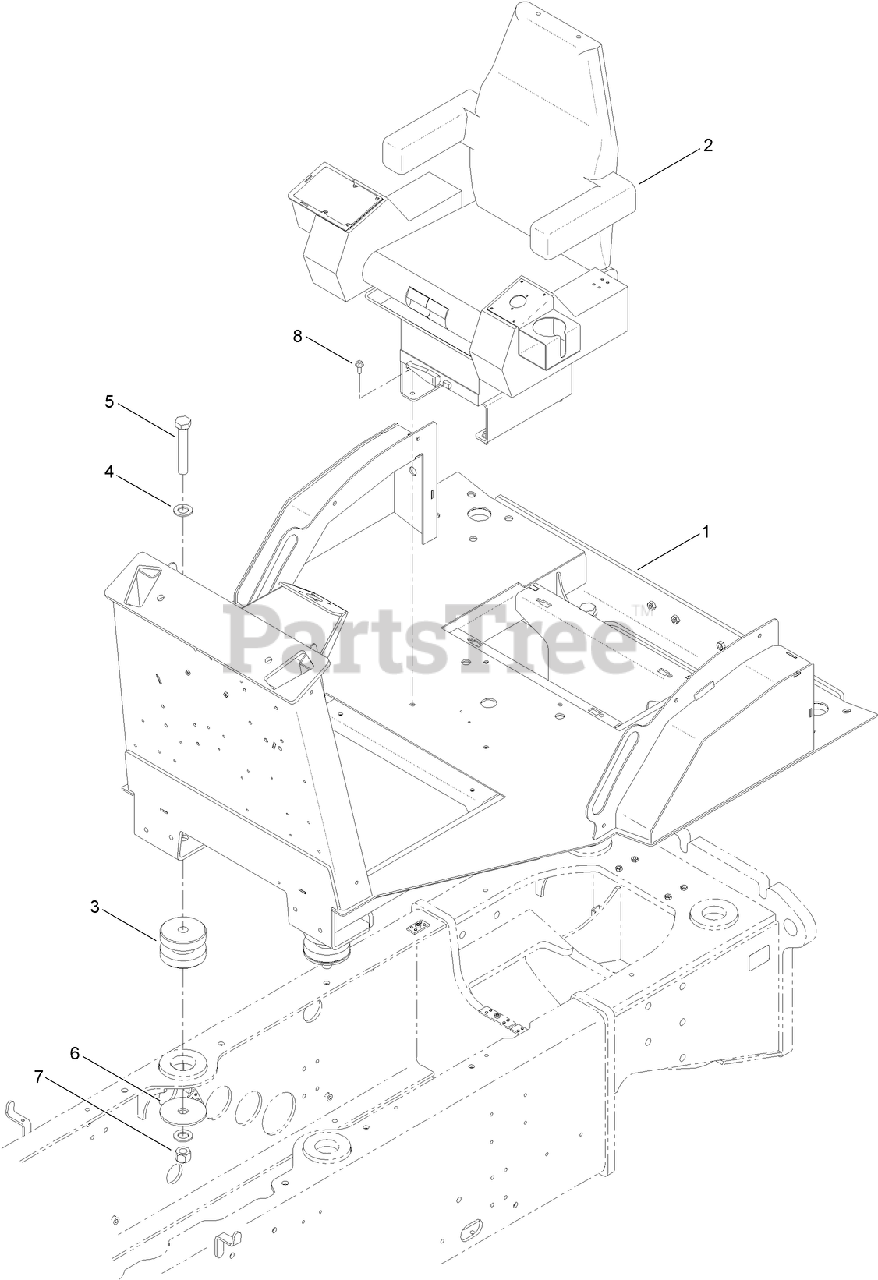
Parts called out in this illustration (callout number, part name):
1	PLATFORM-OPERATOR
2	SEAT ASM
3	MOUNT-RUBBER
5	BOLT-HH
6	WASHER-SNUBBER
8	SCREW-FLANGE
